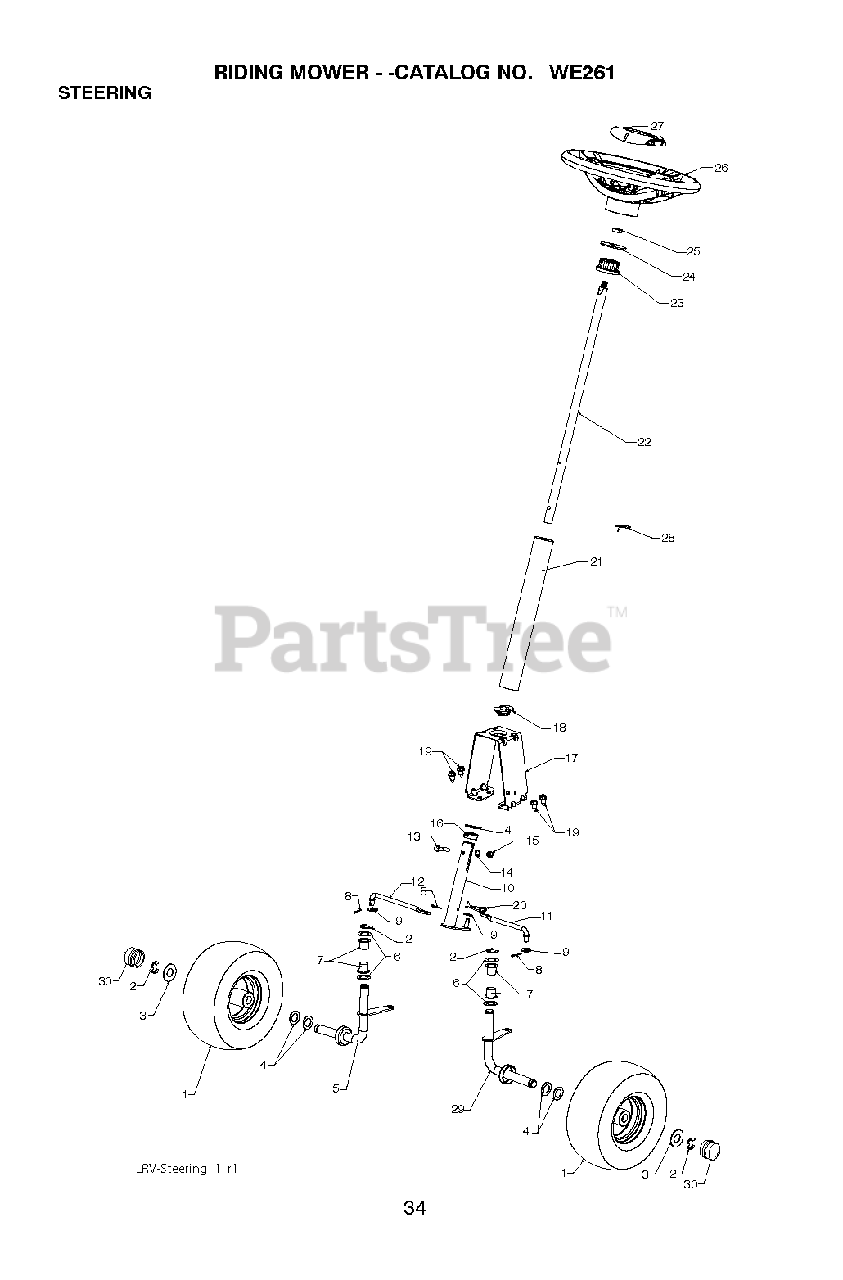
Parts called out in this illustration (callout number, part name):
1	WHEEL.ASM.FRONT.LRV.10" GRAY
2	E-RING LT
3	WASHER.HARDENED
5	SPINDLE.STEERING.RH.LRVA
7	Steering Column Bearing
8	PIN.COTTER.5/64X3/4
10	WELDMENT, LWR STRG SHAFT
11	LINK, STRNG LH LRV
12	LINK.STEERING.RH.LRV
13	HEX BOLT
15	NUT.71038.31-18.HEX.NYLOCK
16	BUSHING, STEERING SNAP
17	SUPPORT, UPPER STEERING
18	BUSHING,STEERING
19	SCREW
20	CLIP.SPRING.STEERINGG
21	FOAM.SHAFT.STEERING
22	SHAFT, STEERING
23	STEERING.WHEEL.ADAPTER
24	WASHER 9/16"ID, 2 3/8""OD
25	NUT.HEX.1/2-20
26	WHEEL.STEER.STDR.498.OVRM.GRAY
27	CAP.WHL.STRNG.STDSRRD.SRS.GREY
28	RETAINER.CLIP.SPRING.S
29	WELDMENT.SPINDLE.LH.LR
30	CAP.HUB.AXLE.LRVA/B
